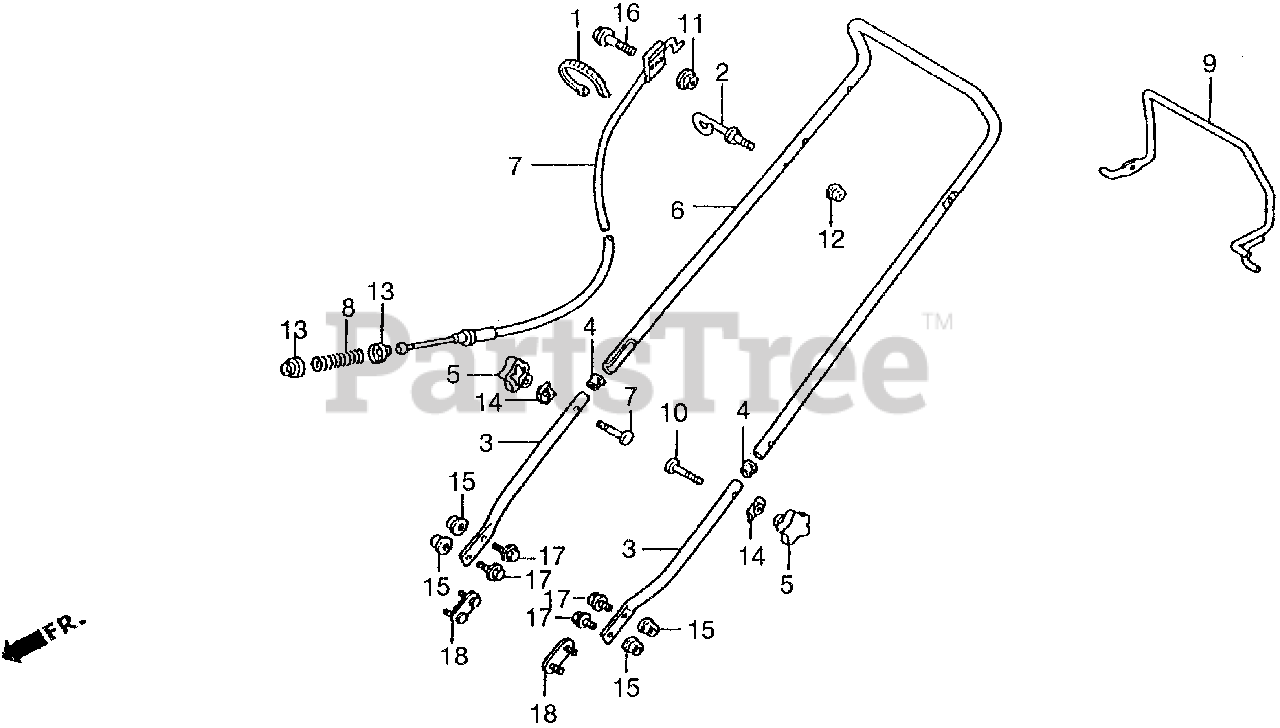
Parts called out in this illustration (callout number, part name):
1	TIE
1	TIE, CABLE (157.5MM)
2	GUIDE, ROPE
3	PIPE COMP,*NH105*
4	CAP, HANDLE (LOWER)
5	GRIP, HANDLE JOINT (UPPER)
6	PIPE, HANDLE (UPPER) (NOT AVAILABLE)
7	CABLE, BRAKE
8	SPRING B, BRAKE
9	LEVER, BRAKE
10	BOLT, HANDLE HOLDER (8X41)
10	BOLT (8X41)
11	NUT, NYLON RING (6MM)
12	NUT, FLANGE (1/4"-20)
13	WASHER, SPECIAL (6MM)
14	WASHER, FRAME JOINT
15	NUT, FLANGE (8MM)
16	BOLT, FLANGE (6X35)
17	BOLT, FLANGE (8X18) Use from Frame SN 1256673.
18	CLAMP, HANDLE
